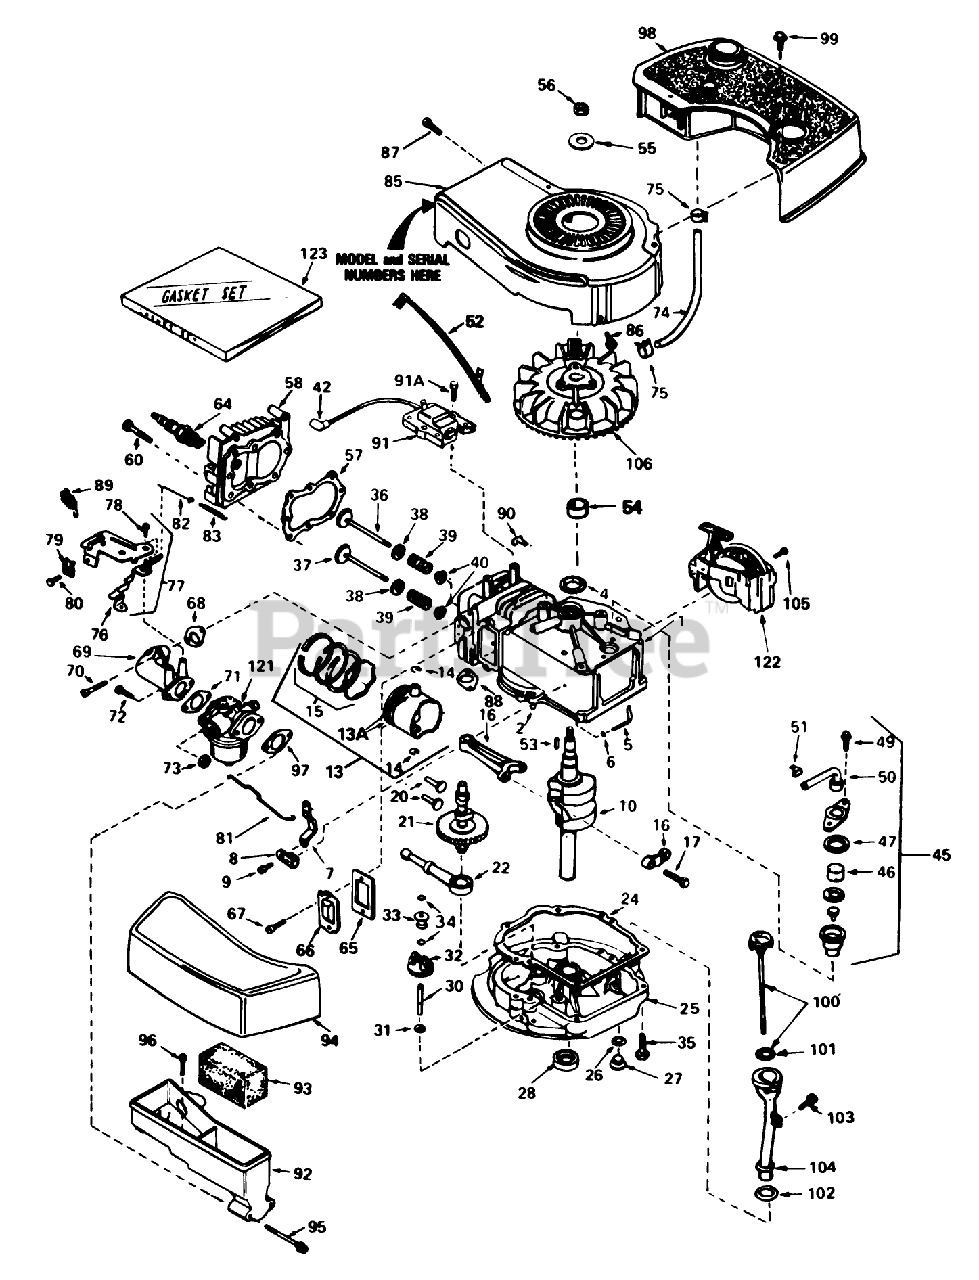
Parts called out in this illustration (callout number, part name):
1	Cyiinder Assy. (Incl. Ref. #2, 4 105)
2	Pin-Dowel
4	Seal-Oil
5	Rod, Governor (Incl. No. 36)
6	Washer-Flat
7	Governor Lever
8	Clamp-Lever, Governor
9	Screw
10	Crankshaft
13	Piston, Pin Ring Assy. (Std.) (Incl. Ref. #13A, 14 15)
13	Piston, Pin Ring Assy. (.010 oversize) (Incl. Ref. #13A, 14 15)
13	Piston, Pin Ring Assy. (.020 oversize) (Incl. Ref. #13A, 14 15)
13A	Piston Pin Assy. (Incl . Ref. . #14) (Std.)
13A	Piston Pin Assy. (Incl. Ref. #14) (.010 Oversize)
13A	Piston Pin Assy. (.020 oversize) (Incl. Ref. #14)
14	Ring-Retaining, Piston Pin
15	Ring Set (Std.)
15	Ring Set (.020" OS)
15	Ring Set (.010" OS)
16	Rod Assy., Connecting (Incl. Ref. #17)
17	Bolt-Rod, Connecting
20	Lifter-Valve
21	Camshaft(Mech.Comp. Release)
22	Oil Pump ASM
24	Gasket, Mounting
25	Flange Assy., Mounting (Incl. Ref. #26thru 30)
26	Gasket-Oil Drain
27	Plug Oil Drain
28	Seal Oil
30	Shaft-Governor
31	Washer-Flat
32	Governor Gear ASM
33	Spool-Governor
34	Ring-Retaining
35	Screw (1/4-20 x 1-1/4)
36	Valve, Intake (Std.) (Incl. Ref. #40)
36	Valve, Intake (1/32" oversize)(Incl. No. 40)
37	Valve, Exhaust (Std.)(Incl. No. 40)
37	Valve, Intake (1/32" oversize)(Incl. No. 40)
38	Cap-Upper Valve Spring
39	Spring-Valve
40	Cap-Valve, Spring
42	Cover-Spark Plug
45	Breather Assy. (Incl. Ref. #46 thru 51)
46	Element-Breather
47	Gasket-Breather
49	Screw (10-24 x 9/16)
50	Tube, Breaker
51	Clip, Breather
52	Wire-Ground
53	Key-Flywheel
54	Spacer
55	Washer-Belleville
56	Nut-Flywheel
57	63573 GIL 42 SNWTHW
58	Head-Cylinder
60	Screw (5/16-18x1-1/2)
64	Plug, Spark (J17LM or equiv.)
64	Plug, Spark (Champion RCJ-8)
65	Gasket-Breather
66	Cover-Valve
67	Screw
68	Gasket-Intake
69	Pipe, Intake (Incl. No. 68)
70	Screw (1/4-20 x 1)
71	Gasket-Carburetor
73	Nut and Lock Washer (1/4-28)
74	Line-Fuel
75	Clamp-Line, Fuel
76	Lever Control
77	Control Assy., Speed (Incl. Nos, 76, 78 89)
78	Screw, Hex Washer Hd Shoulder Self-Tap
79	Conduit
80	Screw (10-32 x 3/8)
81	Link-Throttle
82	Link Governor Spring
83	Spring Governor
85	Housing-Blower
86	Screw (1/4-20x19/32)
87	Screw (10-24 x 9/16)
88	Gasket Exhaust
89	Terminal
90	Clip-Wire
91	Solid State
91A	Screw
92	Body Air Cleaner
93	Filer, Air
94	Cove, Air Cleaner
95	Screw Fil Hd.
96	Screw, Hex Hd.
97	Gasket-Air Cleaner
98	Tank-Fuel
99	Screw (10-32 x 35/64)
100	Dipstick, Oil (Incl. Ref. #101)(Twist Lock)
101	O-Ring
102	Gasket
103	Screw (10-32 x 1/2)
104	Tube-Oil Fill
105	Screw (1/2-20x5/8)
106	Flywheel
121	Carburetor (Incl. Ref. #71)
122	Starter-Sidemount
123	Gasket Set
